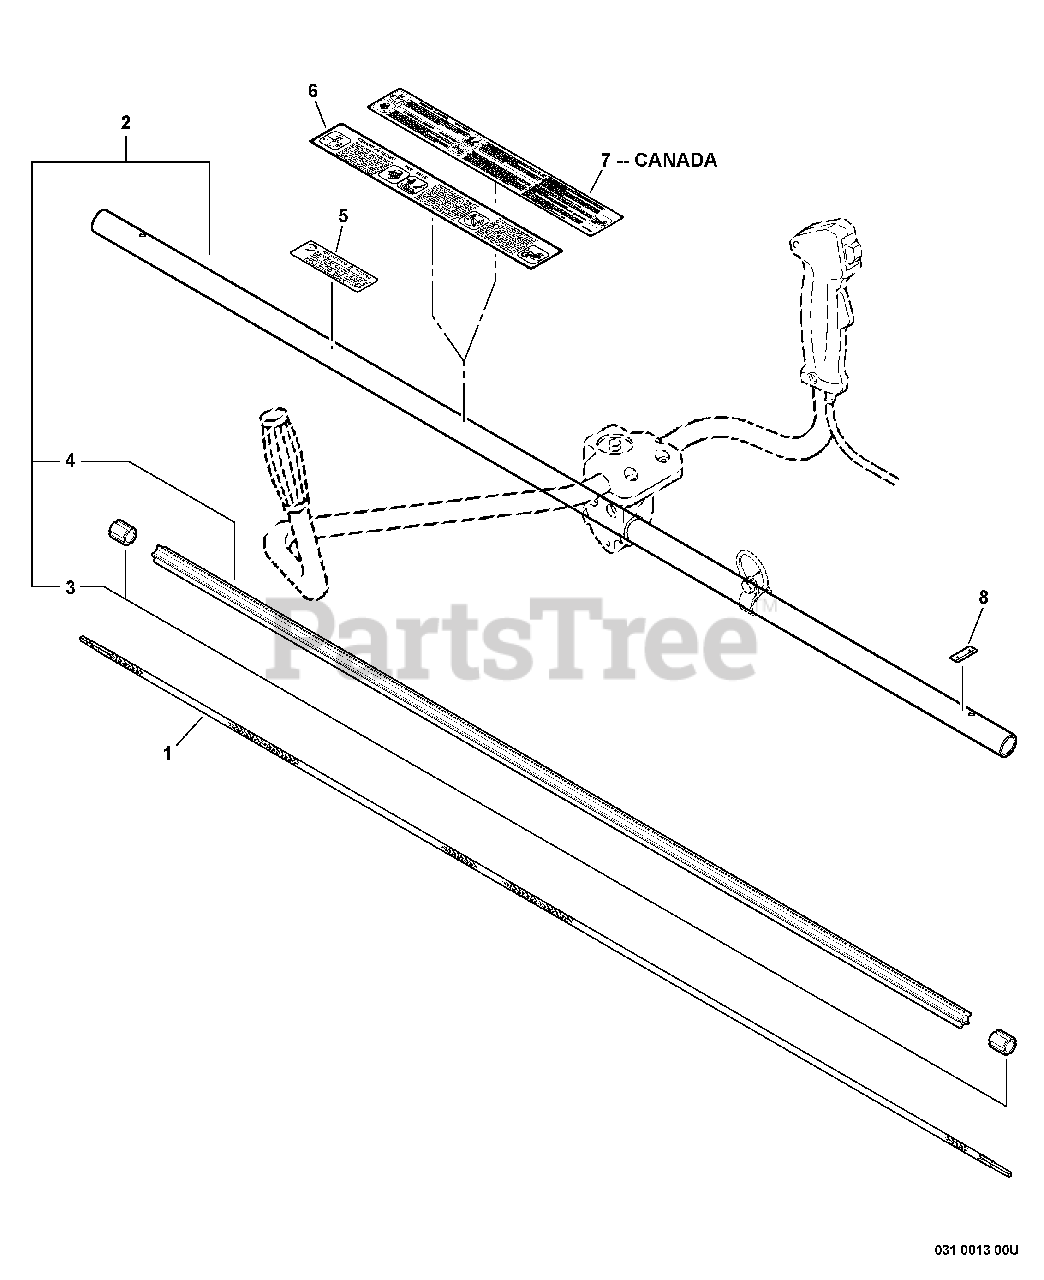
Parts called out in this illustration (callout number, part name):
1	DRIVESHAFT - FLEXIBLE
2	MAIN PIPE ASSY
4	LINER - FLEXIBLE
5	LABEL - CAUTION -- SPANISH
6	LABEL - CAUTION
7	LABEL - CAUTION
8	LABEL - ALIGNMENT
